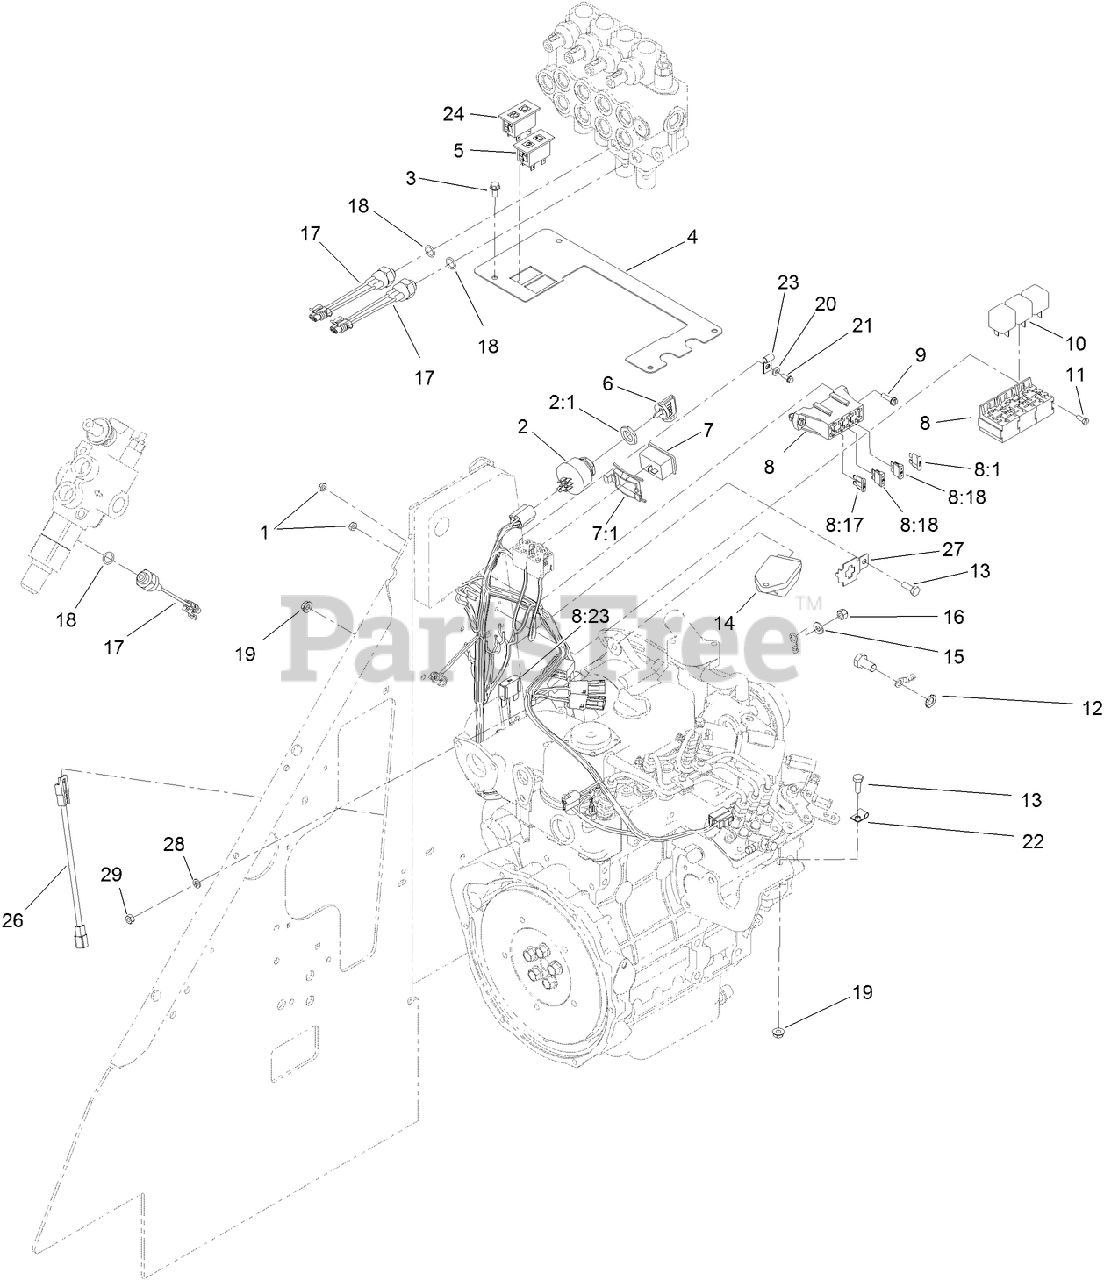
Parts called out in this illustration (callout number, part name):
1	NUT-LOCK, NI
2	SWITCH ASM
2:1	NUT-HH
2:2	WASHER-LOCK
3	SCREW-HWH
4	PLATE-COVER
5	LAMP-WARNING
6	KEY-IGNITION
7	HOUR METER ASM
7:1	CLIP-MOUNTING
8	HARNESS-WIRE
8:1	FUSE-40 AMP
8:17	FUSE-BLADE, 7.5 AMP
8:18	FUSE-BLADE, 15 AMP
8:23	FUSE-BLADE, 50 AMP
9	SCREW-HWH
10	RELAY
11	SCREW-SHH
12	WASHER-LOCK
13	SCREW-HH
15	WASHER-SPRING
16	NUT-HEX
17	SWITCH-BALL
18	O-RING
19	NUT-HF
20	WASHER-FLAT
21	SCREW-HWHTF
22	CLAMP-BODEN
23	CLIP-CLOSED, INSULATED
24	LAMP-WARNING
26	HARNESS-LINK, FUSIBLE
27	CLIP-FUSE
28	WASHER-LOCK, SPRING
29	NUT-HEX
